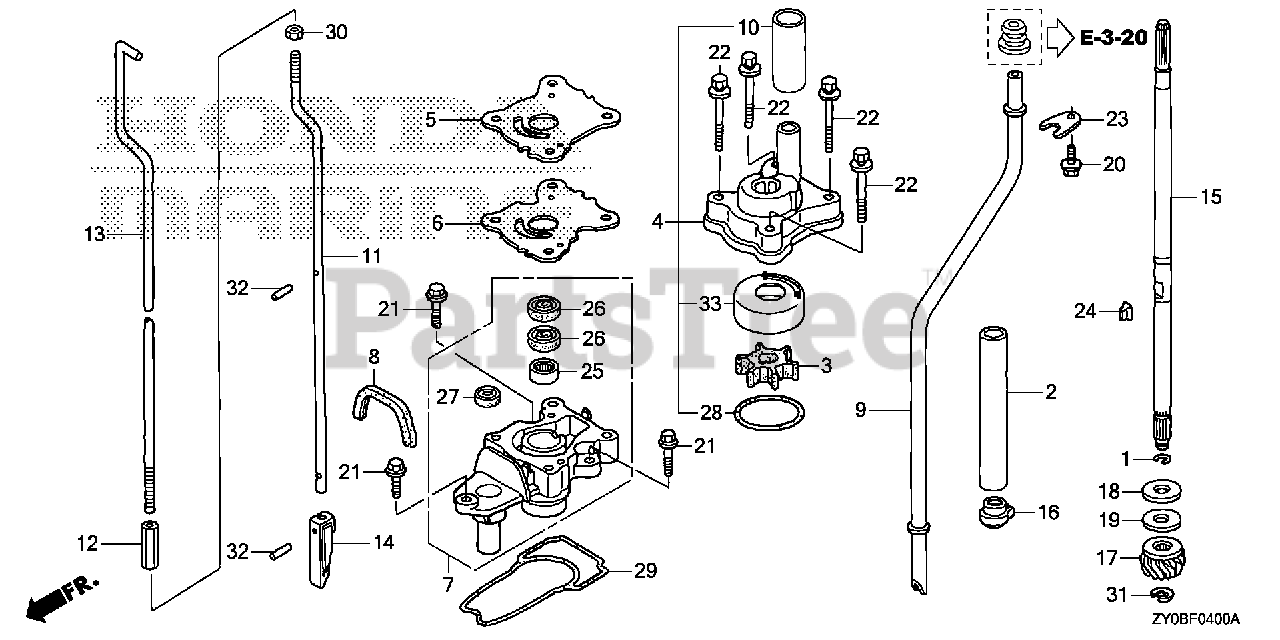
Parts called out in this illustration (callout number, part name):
1	CLIP, VALVE GUIDE
2	GUIDE, OIL (S,L)
3	IMPELLER, PUMP (UL)
4	HOUSING ASSY., IMPELLER
5	COVER, IMPELLER
6	GASKET, IMPELLER
7	HOUSING, WATER PUMP (S,L)
8	GROMMET, WATER PUMP HOUSING
9	TUBE, WATER (L)
10	RING, WATER TUBE SEAL
11	ROD B, SHIFT (L)
12	JOINT, SHIFT ROD
13	ROD A, SHIFT (L)
14	ROD, PUSH
15	SHAFT, VERTICAL (L)
16	SLINGER, OIL (UL)
17	GEAR, PINION
18	WASHER A, THRUST BEARING
19	WASHER B, THRUST BEARING
19	WASHER C, THRUST BEARING
20	BOLT, FLANGE (6X12) Use from Frame SN 1005249.
21	BOLT, FLANGE (6X20) (ENGINE NO.)
22	BOLT-WASHER (6X50)
23	PLATE, WATER TUBE SETTING
24	KEY, WOODRUFF
25	BEARING, NEEDLE (15X21X12)
26	SEAL, WATER (15X24X5)
27	SEAL, WATER (6MM)
28	O-RING (42.2X2.4)
29	O-RING, WATER PUMP HOUSING
30	NUT, HEX. (6MM)
31	E-RING (8MM)
32	ROLLER (2.5X11.8)
33	LINER, PUMP
